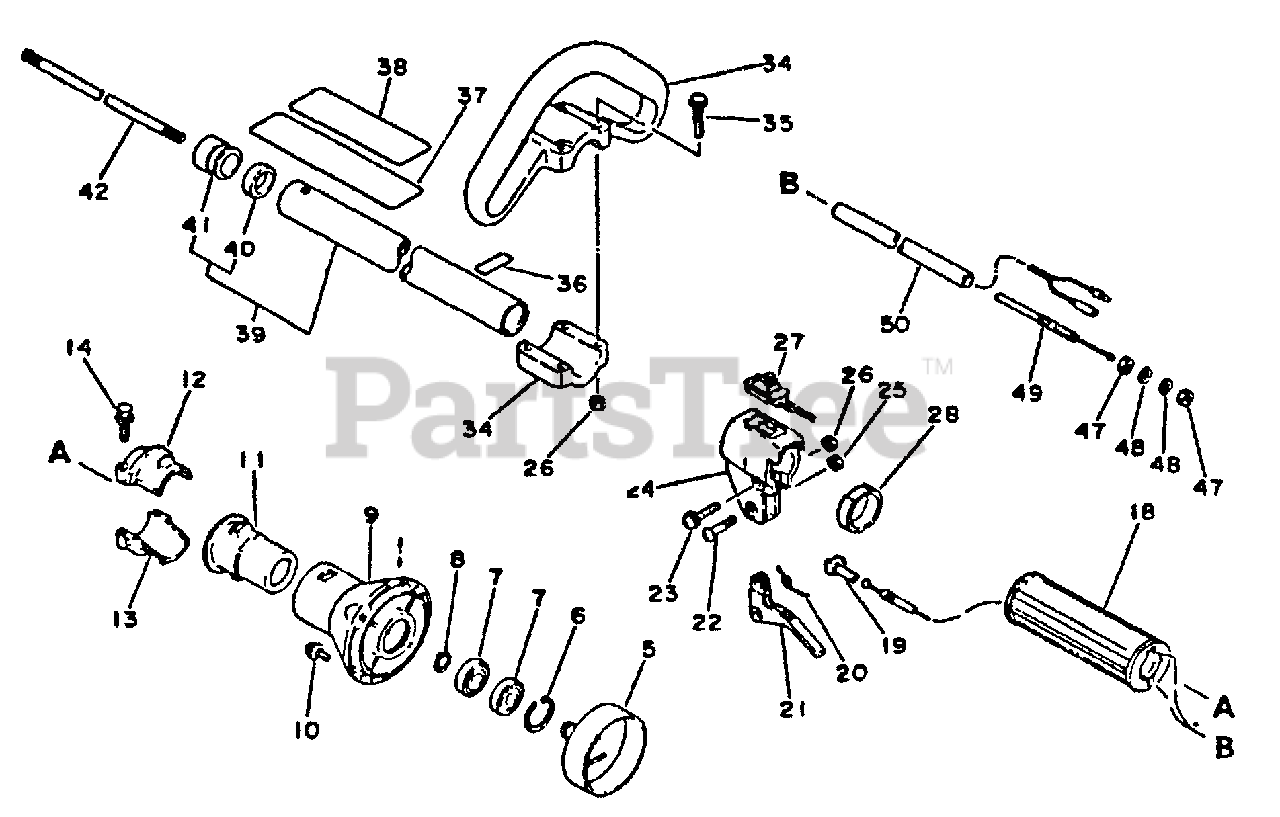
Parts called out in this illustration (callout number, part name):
5	DRUM, CLUTCH
6	RING, RETAINING - 28
7	BEARING, BALL - 6001
8	RING, RETAINING - 12
9	CASE, CLUTCH
10	SCREW - 5X16
12	CLAMP, MAIN PIPE
13	CLAMP, MAIN PIPE
14	BOLT - 5X25
18	GRIP, HANDLE
19	GUIDE, CABLE
20	SPRING, TRIGGER
21	TRIGGER, THROTTLE
22	SCREW - 5X30
23	SCREW - 5X30
24	BRACKET, TRIGGER
25	LOCKNUT - 5
27	IGNITION SWITCH ASSY
34	LOOP HANDLE ASSY
35	SCREW - 5X35
37	LABEL - CAUTION
38	LABEL - CAUTION
39	MAIN PIPE ASSY
42	DRIVESHAFT - SOLID
48	WASHER - 6
49	CABLE, THROTTLE
50	TUBE - VINYL
